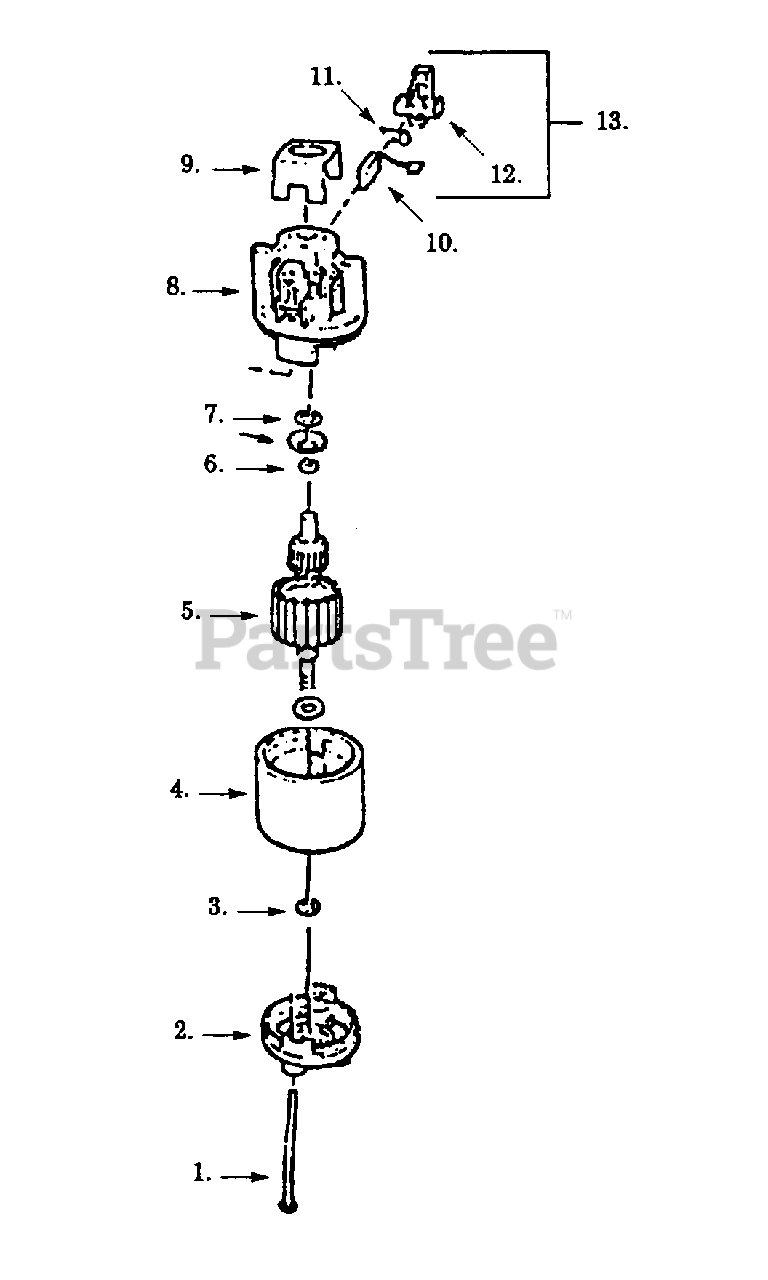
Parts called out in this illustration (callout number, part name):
2	Endbell Ass'y. (Drive)
4	Field Ass'y.
5	Armature Ass'y.
8	Endbell Ass'y. (Brush)
9	Insulator
10	Carbon Brush
11	Brush Spring
12	Brush Holder
13	Brush Kit (Incl. 10,11,12)
14	Retaining Ring
